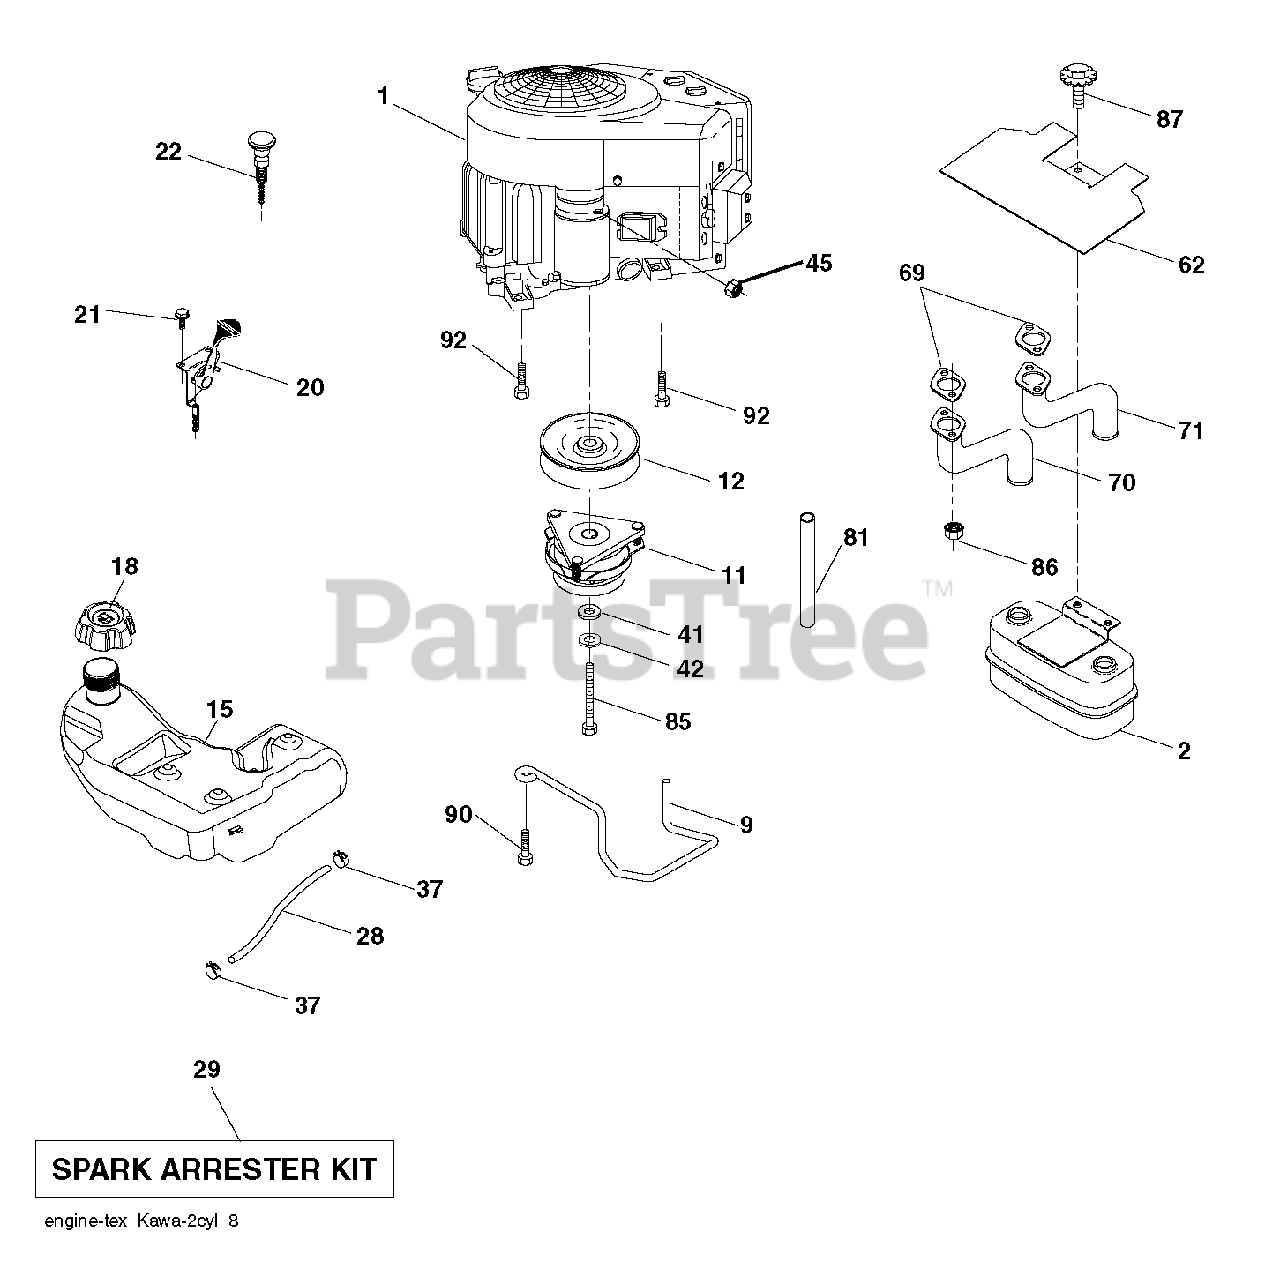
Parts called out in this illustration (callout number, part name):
2	MUFFLER.ASM.TWN.EXTNDED.DFLCTR
9	KEEPER.BELT.ENGINE.4.2
11	CLUTCH MZ ZTR GT.48/54"1.125"
12	PULLEY ENGINE
15	TANK.FUEL.4GAL
18	CAP.FL.R.3'N/CARB.H.CROWN.498
20	CONTROL.THROTTLE.COBRA.BLACK
21	SCREW.#10 X 0.750.BOS
22	CONTROL, CHOKE
28	REPL BY 532 00 85-43
29	KIT.SPARK ARRESTOR 794945 B&S
37	HOSE CLAMP
42	LOCKWASHER
45	NUT
62	SHIELD.HEAT.MUFFLER
70	TUBE.EXHAUST.LH.FR961/FR730
71	TUBE.EXHAUST.RH.FR961/FR730
81	TUBE, DRAIN OIL ASM.
85	BOLT HEX 7/16-20 X 3.75 GR. 5
86	NUT.HEX.FLANGE.TOPLOCK
87	BOLT, 5/16-18 X 1 3/4
90	SCREW 3/8-16X1
92	SCREW 3/8-16X1
